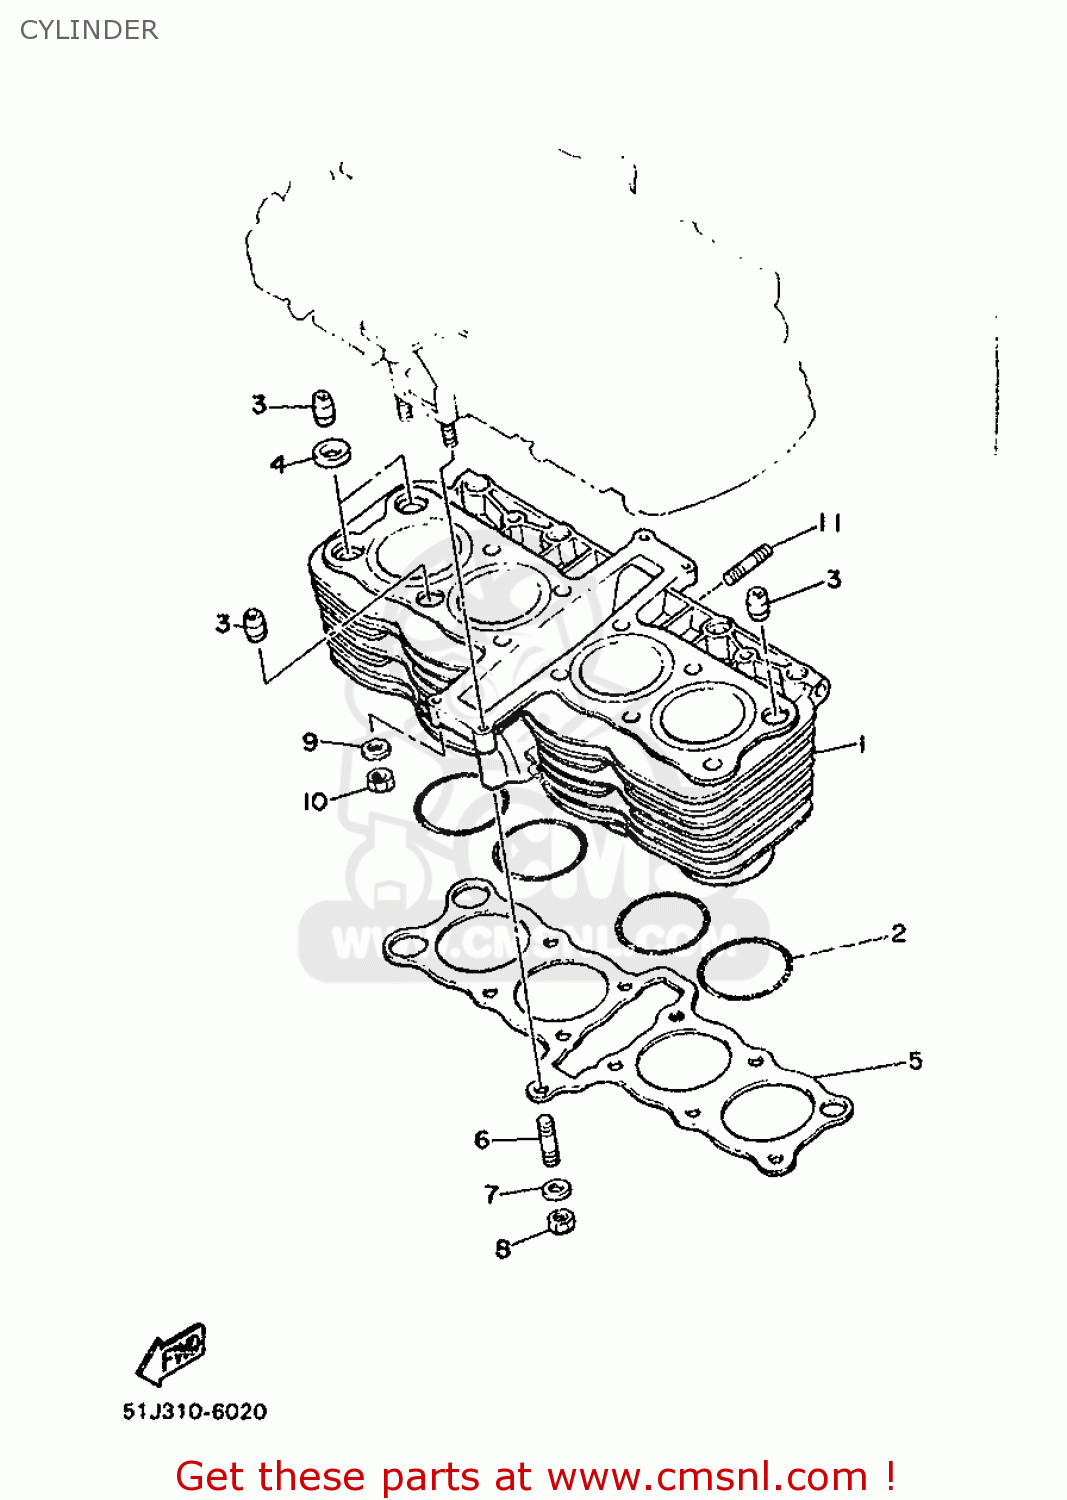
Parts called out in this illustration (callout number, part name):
01	CYLINDER
02	O-RING (4U8)
03	PIN, DOWEL
04	GASKET (1L9) (NAS)
05	GASKET, CYLINDER (NAS)
06	BOLT, STUD (4H7)
07	WASHER, PLATE (33N)
08	NUT
09	WASHER(526)
10	NUT (409)
11	BOLT, STUD (4V8)
